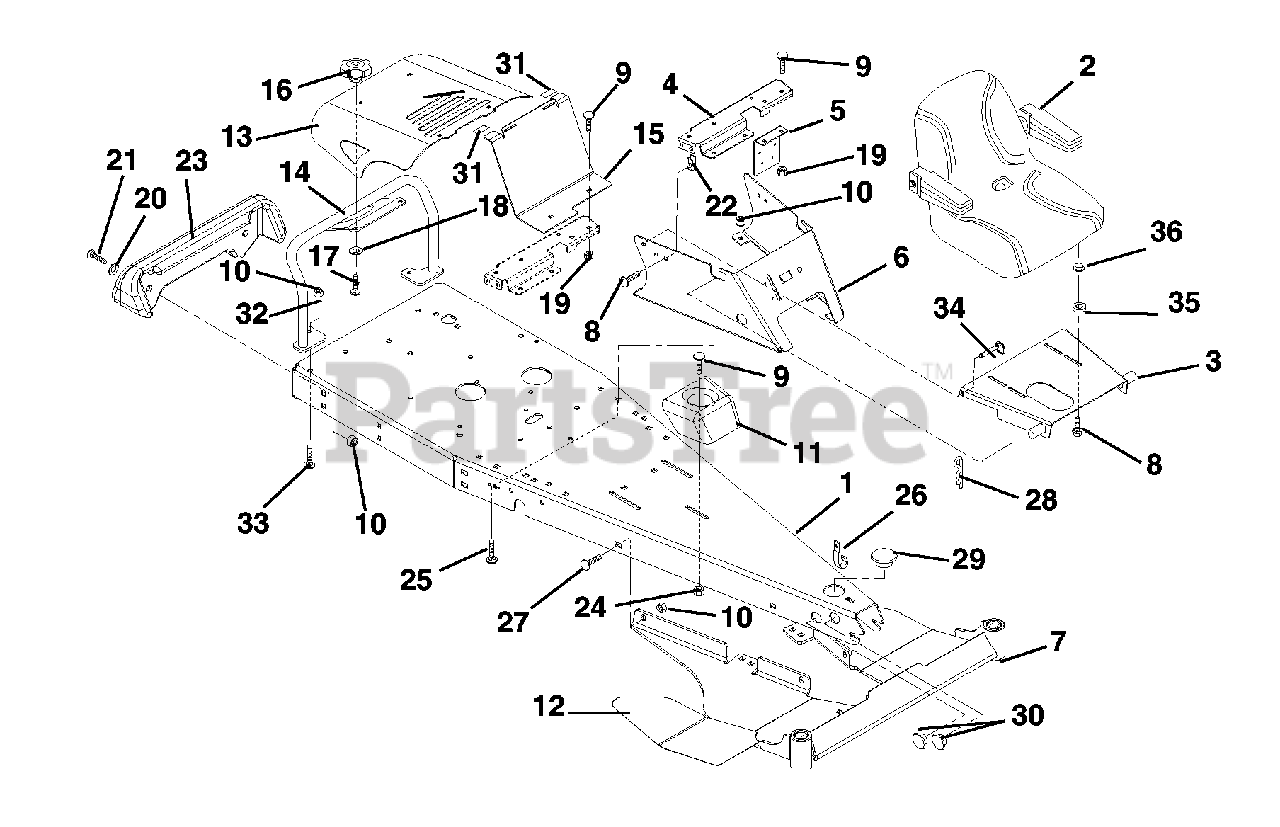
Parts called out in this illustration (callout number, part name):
2	Seat, TS2500 Michigan with Arm
3	Weldment, Seat Plate
4	Reforcement, Seat Support
5	Panel, Solenoid Mounting
6	Seat Support
7	Weldment, Footrest
8	Bolt, Serrated Hex Flange Washer Head .31-18 x 1
9	Bolt, Round Head Square Neck .31-18 x .75 Grade 5
10	Nut, Locking Top Flange .38-16
11	Cupholder
12	Grip, Left Hand Foot Rest
12	Grip, Right Hand Foot Rest
13	Engine, Hood (032)
14	Weldment Tube (032)
15	Bracket, Hood Support (032)
16	Knob, Clamping .31-18 Nyloc (032)
17	Bolt, Round Head Square Short Neck .31-18 x .75 Grade 5 (032)
18	Nut, Push .312 (032)
19	Nut, Locking Top Flange .31-18 (032)
20	Washer, Flat Steel .438 x 1.00 x .083
21	Bolt, Hex .38-16 x 1.75 Grade 5
22	Nut, Retainer .25-20 x .56
23	Weight, Sport Zoom
24	Nut, Spin Lock Flange .312-18
25	Bolt, Round Head Square Neck .38-16 x .75 Grade 5 (032)
26	J, Clamp
27	Bolt, Round Head Square Neck .38-16 x 1.00 Grade 5
28	Pin, Hair External .12 x .31 x 2.37
29	Hole Plug, 1.38
30	Hole Plug, 1.00
31	Tape, Foam .12 x 1.00 Vinyl
32	Retainer, .38 Push-On
33	Bolt, Round Head Square Neck .38-16 x 1.00
34	Pin, Detent with Ring .25 x 1.00
36	Nut-Push .312
